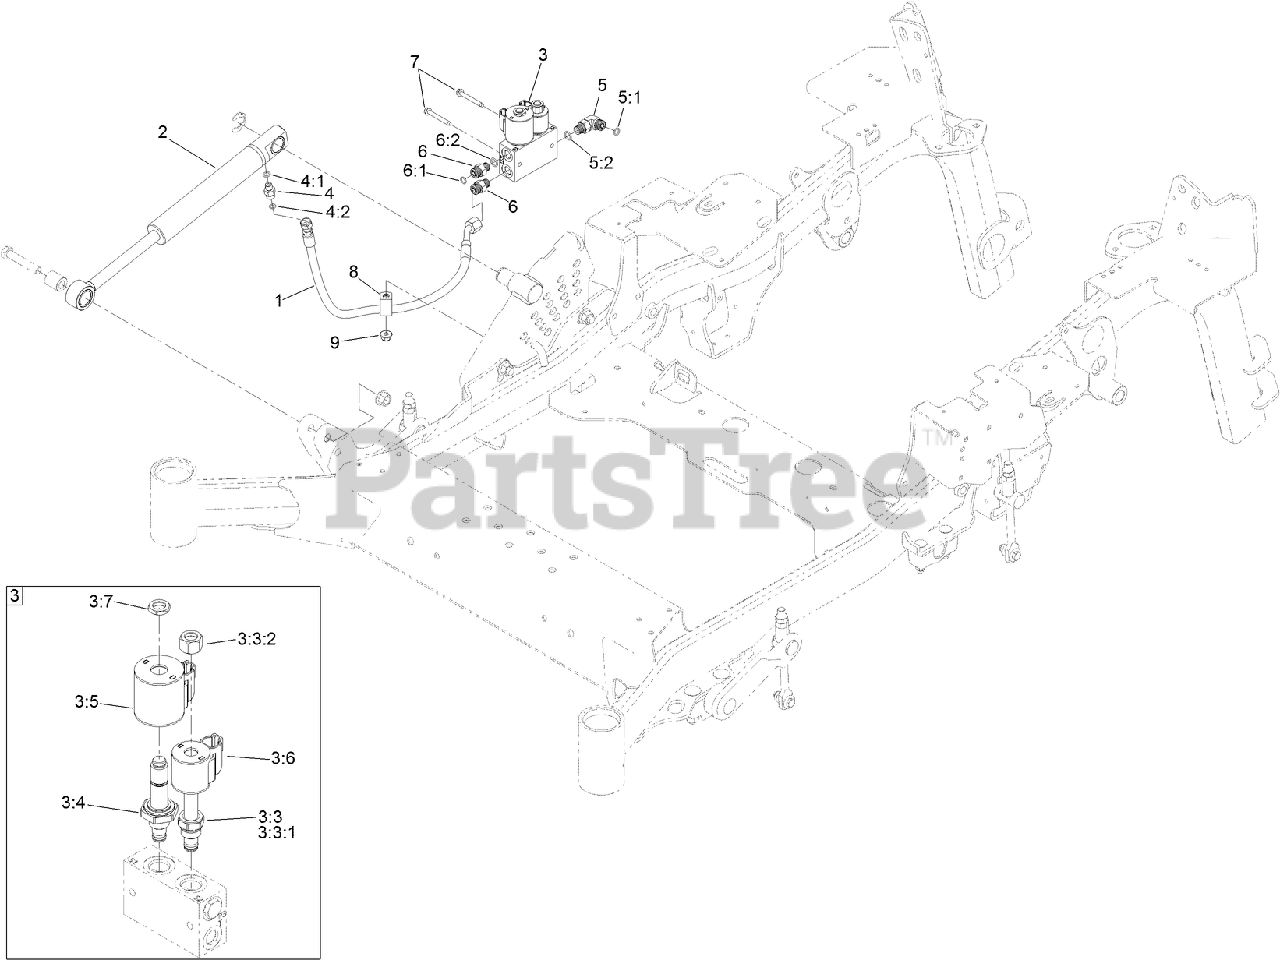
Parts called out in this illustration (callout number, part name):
1	HOSE ASM
2	CYLINDER-LIFT
3	DECK LIFT VALVE ASM
3:3	VALVE-SOLENOID
3:3:1	SEAL KIT
3:3:2	NUT-SOLENOID
3:4	VALVE-SOLENOID
3:5	COIL-12V
3:7	NUT-COIL
4	FITTING-HYD, STRAIGHT
4:1	O-RING
4:2	O-RING
5	FITTING-ELBOW, 90 DEG
5:1	O-RING
5:2	O-RING
6	FITTING-STRAIGHT
6:1	O-RING
6:2	O-RING
7	SCREW-HWHTF
8	CLIP-LOOM
9	NUT-HF, NI
